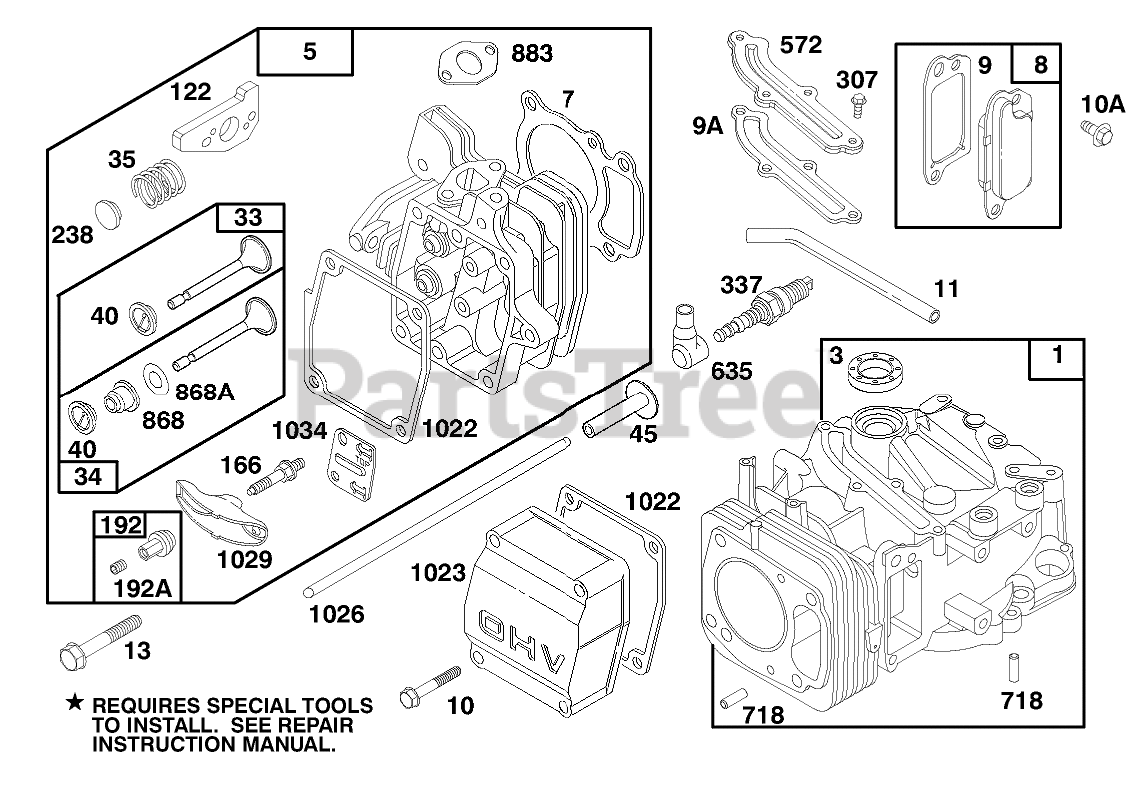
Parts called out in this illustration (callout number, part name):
1	CYLINDER ASSEMBLY
3	SEAL - OIL
5	CYLINDER HEAD
7	CYLINDER HEAD GASKET
8	Breather Assy
9	BREATHER GASKET
9A	GASKET-BREATHER
10	HEX HEAD SCREW
10A	HEX HEAD SCREW
11	TUBE - BREATHER
13	CYLINDER HEAD SCREW
33	EXHAUST VALVE
34	INTAKE VALVE
35	VALVE SPRING
40	SPRING RETAINER
45	VALVE TAPPET
122	ADAPTER ASSEMBLY
166	ROCKER ARM STUD
192	NUT - HEX SPECIAL
192A	SCREW SET
238	VALVE CAP
307	SCREW - SEM
337	PLUG-SPARK
572	BAFFLE - CYCLINDER
635	SPARK PLUG ELBOW
718	DOWEL - SLEEVE
868	SealAssy-Valve
868A	Seal-Valve
883	EXHAUST GASKET
1022	ROCKER COVER GASKET
1023	COVER - VALVE
1026	PUSH ROD
1029	ROCKER ARM
1034	PUSH ROD GUIDE
